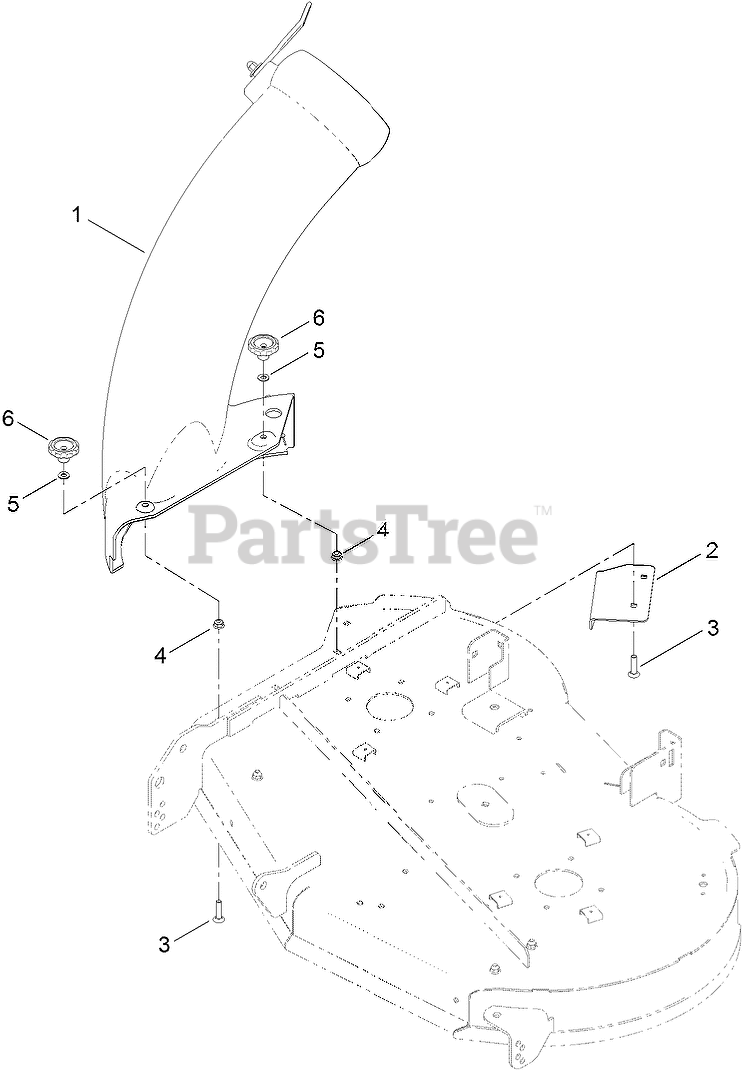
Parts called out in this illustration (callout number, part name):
1	CHUTE ASM
2	BAFFLE-CUTOFF
3	SCREW-CARR
4	NUT-HF, NI
5	WASHER-PLAIN
